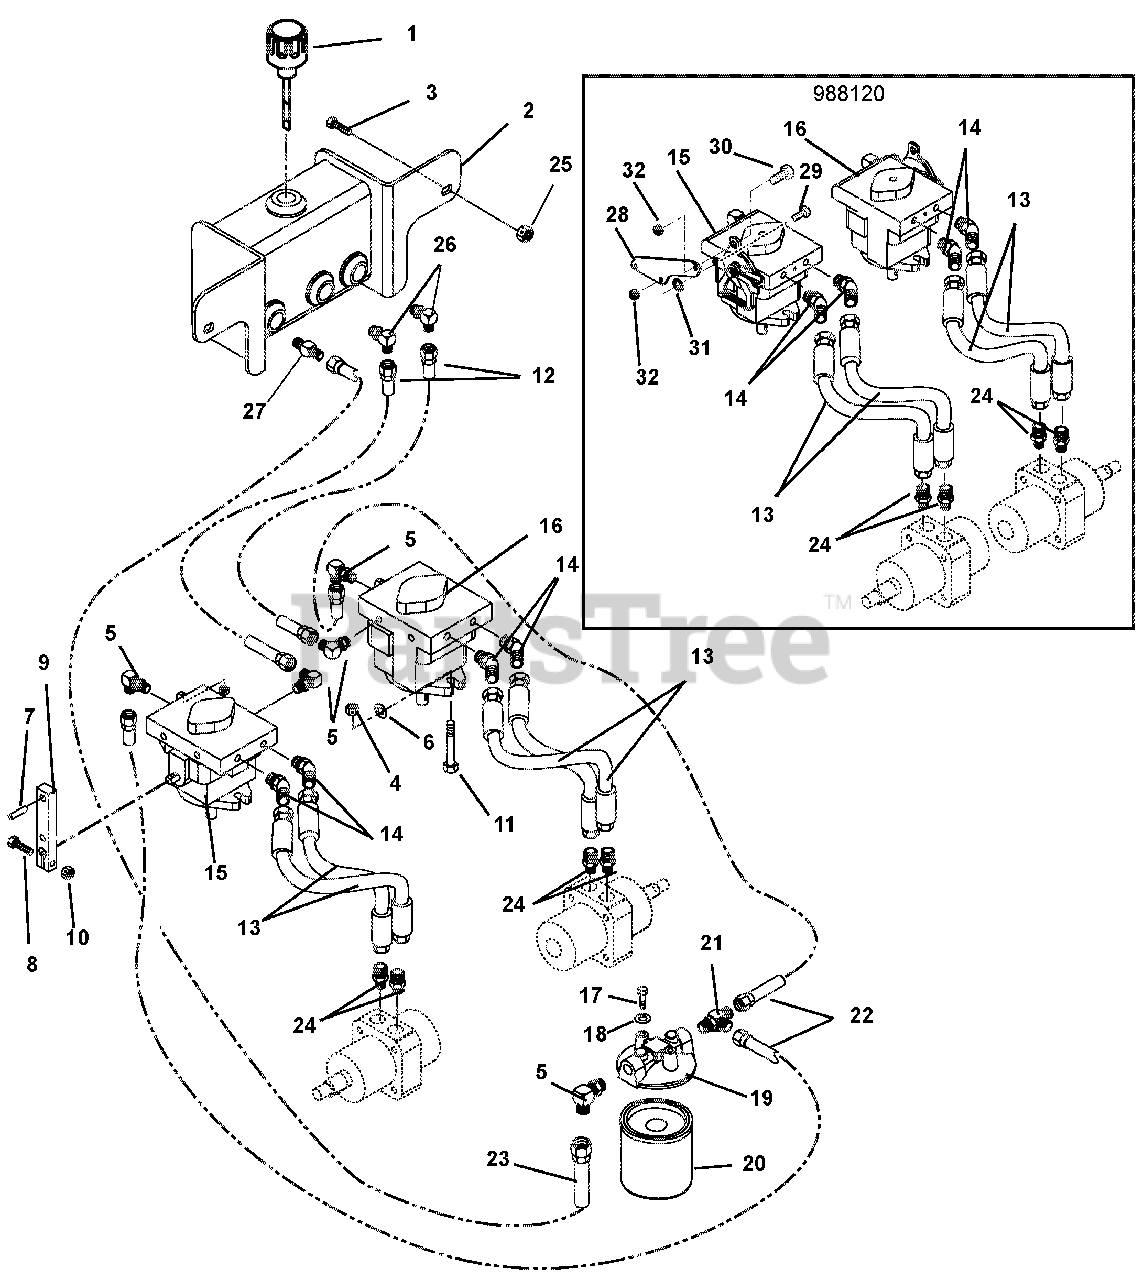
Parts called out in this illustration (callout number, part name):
1	Breather, Dipstick
2	Tank Assembly, Hydraulic
3	Bolt-Hex .38-16 x 1.00 Grade 5
4	Nut-Nylon-Locking .44-14
5	Fitting, Hydraulic
6	Washer-Flat-Steel .43 x 1.00 x .16
7	Pin-Dowel .312 x 1.25 (105, 108)
8	Bolt-Hex .25-20 x 1.25 Grade 5 (105, 108)
9	Arm, Pump Actuating (105, 108)
10	Nut-Locking-Nylon .25-20 (105, 108)
11	Bolt-Hex .44-14 x 1.50 Grade 5
12	Hose, Hydraulic
13	Hose, Hydraulic
14	Fitting, Hydraulic
15	Pump, Hydraulic Right Hand (105, 108, 123, 126)
15	Pump, Hydraulic Right Hand w/ Return (120, 124, 125, 127)
16	Pump, Hydraulic Left Hand (105, 108, 123, 126)
16	Pump, Hydraulic Left Hand w/ Return (120124, 125, 127)
17	Bolt-Hex .25-20 x .50 Grade 5
18	Washer-Locking .25 x .062 Regular
19	Head, Filter
20	Filter- Oil
21	Fitting, Hydraulic Tee
22	Hose, Hydraulic
23	Hose, Hydraulic
24	Fitting 12MP-6FP BROYHILL# TM5406-12-6
25	Nut-Locking-Nylon .38-16
26	Hydraulic, Fitting Elbow
27	Hydraulic, Fitting Straight
28	Bracket, Return to Neutral/Damper (120)
29	Bolt-Hex .31-18 x .50 Grade 5 (120)
30	Bolt-Hex .31-18 x 1.00 Grade 5 (120)
31	Bushing-Sleeve .377 x .624 x .370 (120)
32	Nut-Locking-Center .31-18 (120)
